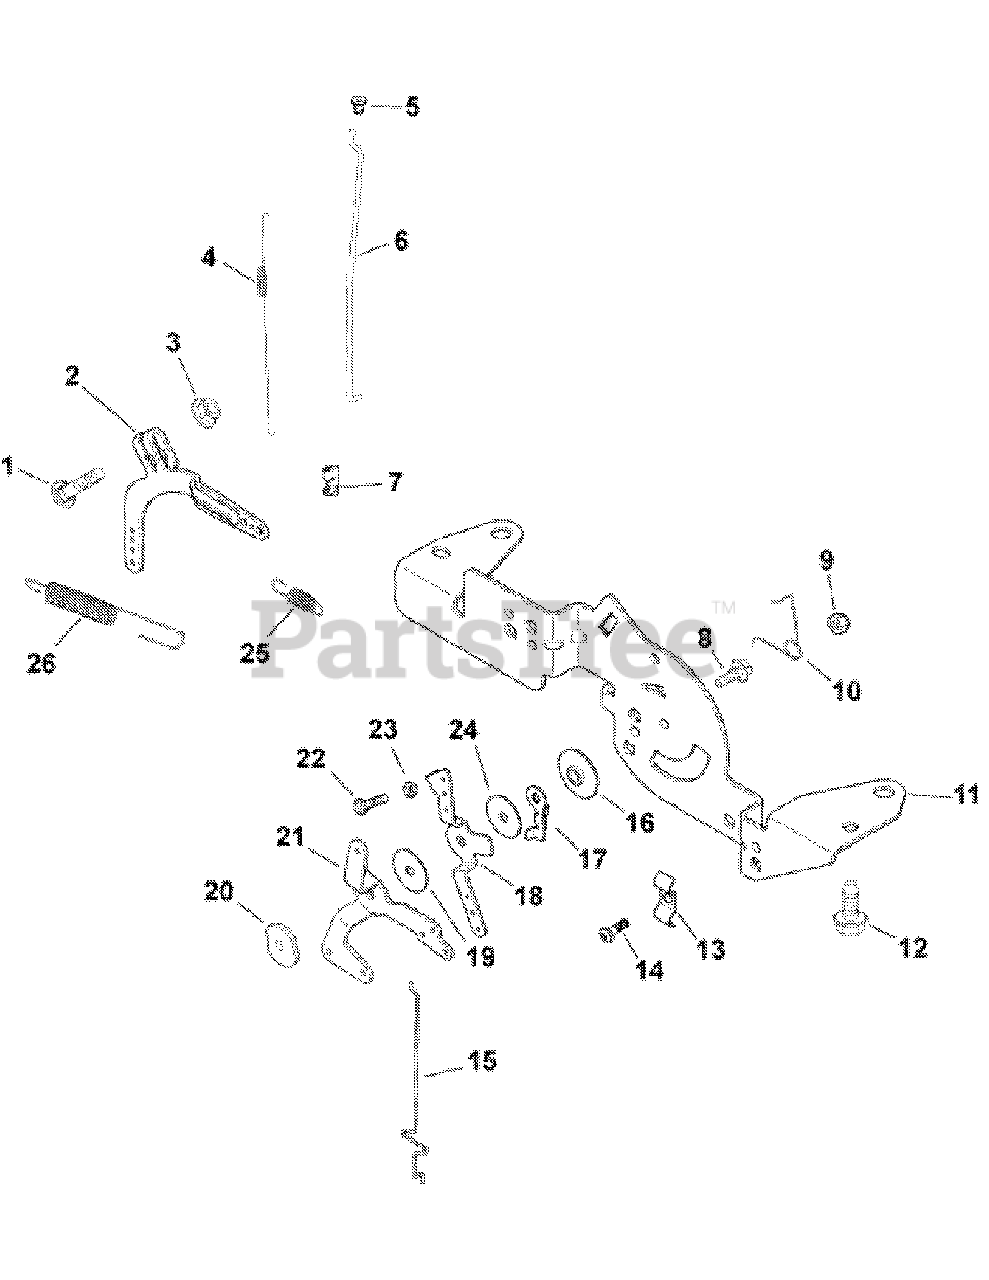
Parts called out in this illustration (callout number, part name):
1	BOLT, RD HD SQ NECK M6X1.0X25
2	LEVER, GOVERNOR
3	NUT, FLG M6X1.0
4	SPRING, LINKAGE
5	BUSHING, LINKAGE RETAINING
6	LINKAGE, THROTTLE
7	BUSHING, THROTTLE LINKAGE
8	SCREW, FLG THD FRM M5X.8X16
9	NUT, LOCK M5X.8
10	SPRING, CHOKE RETURN
11	BRACKET, CONTROL - USE 24 126 172-S
12	SCREW, FLG THD FRM M6X1.0X16
13	CLAMP, DUAL CONDUIT
14	SCREW, LBD THD FRM M5x0.8x16
16	SPACER, CONTROL ASSEMBLY
17	LEVER, THROTTLE ACTUATOR
18	LEVER, THROTTLE CONTROL
19	WASHER, FLAT 5.5 MM
20	WASHER, SPRING 1/4"
22	SCREW, SLT HD CAP M4X0.7X25
24	WASHER, FLAT 5 MM
25	SPRING, GOVERNOR
26	SPRING, GOVERNOR
